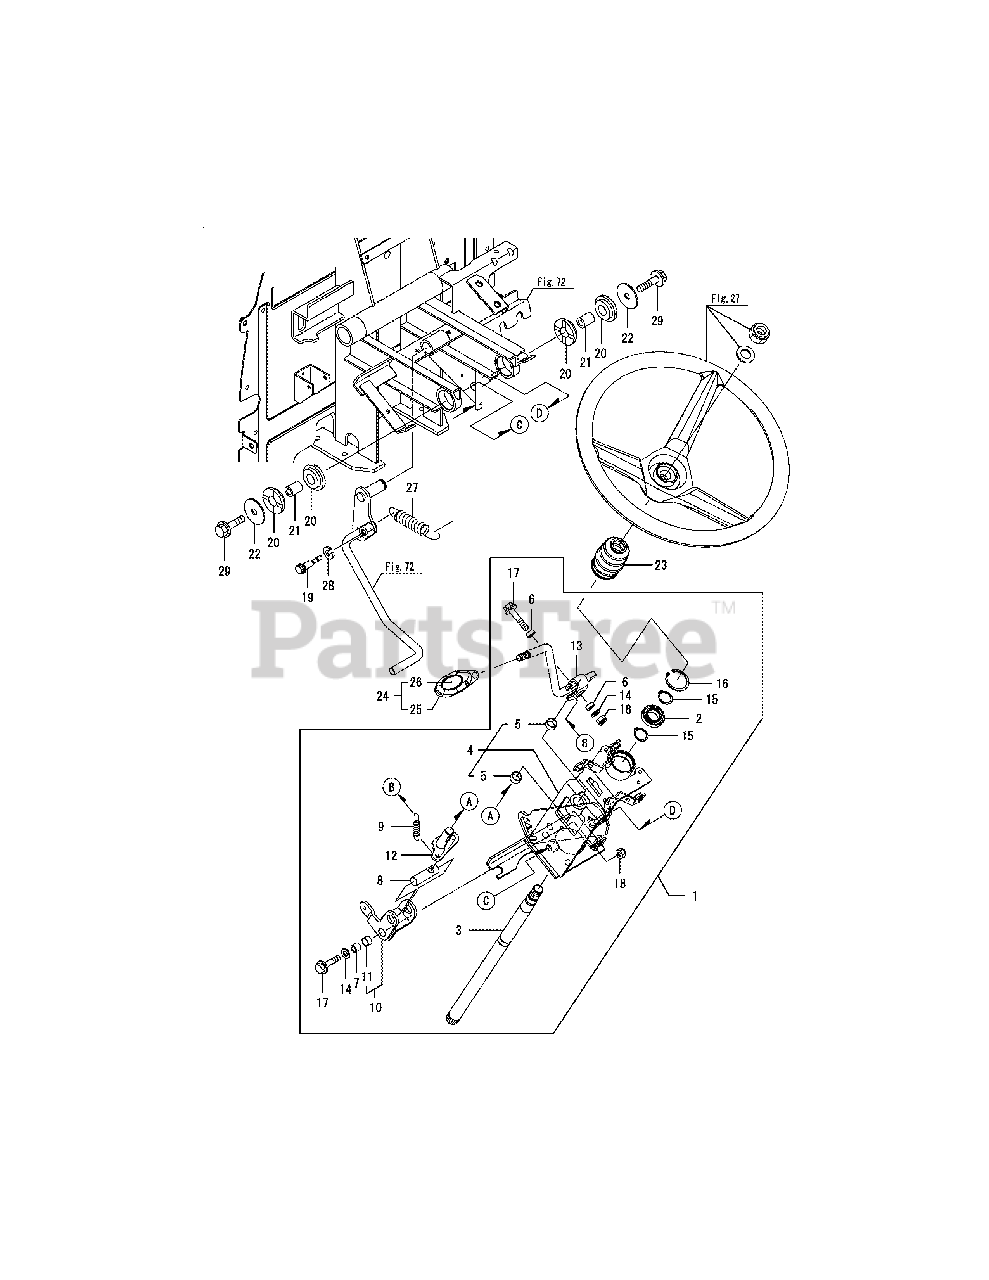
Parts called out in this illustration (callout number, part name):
1	COLUMN UNIT, STEERING
2	BEARING, 6904LLU
3	SHAFT, STEERING
4	COLUMN ASSY, STG
5	BEARING, 15 X 8
6	COLLAR, 8.2X14X5.3
7	COLLAR, 12X8X10
8	PIN, CONNECTING
9	SPRING, RETURN
10	ARM ASSY, REVERSER
12	SHAFT, REVERSER
13	LEVER, REVERSER
14	WASHER 8, POLISHED
17	BOLT M 8X 35 PLATED
19	PIN, TILT LOCK
21	COLLAR, 17.3X10X22
22	WASHER, 10.5X44X2.3
23	BOOT, STEERING
24	KNOB; REVERSER LEVER
28	SPRING WASHER 10
29	BOLT M10X 40 PLATED
